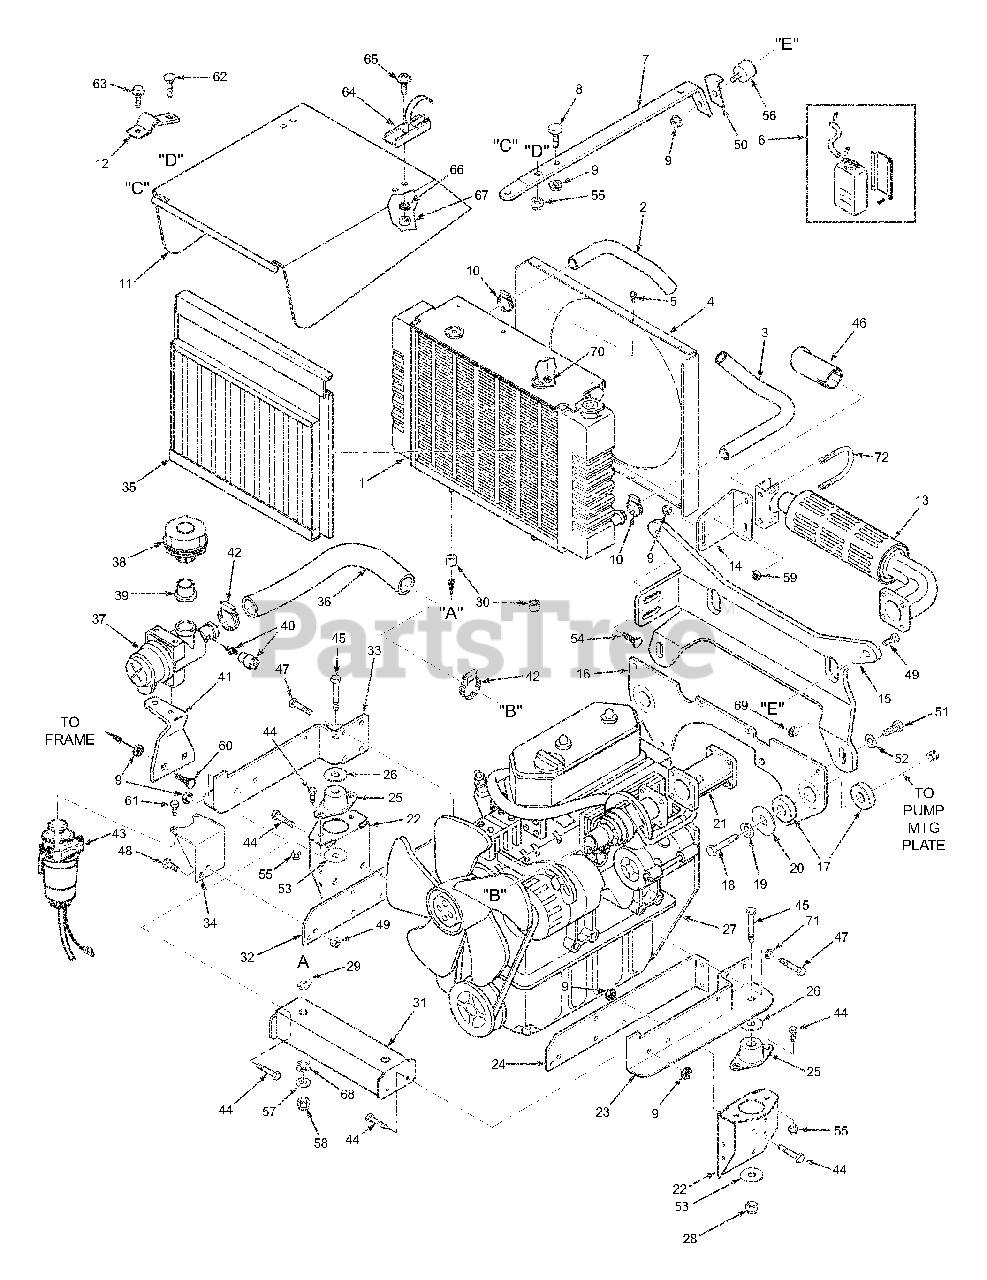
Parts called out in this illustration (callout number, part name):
1	Radiator
2	Hose, Upper Radiator
3	Hose, Lower Radiator
4	Shroud, Fan
5	Screw. #10-32 x 1/2"
6	Coolant Tank Assembly w/hose
7	Support Bracket, Hood
8	Bumper, Rubber
9	Nut, Serrated Flange 5/16-18
10	Clamp, 1-1/2" Dia.
11	Hood Weldment
12	Hinge, Hood
13	Muffler with Guard
14	Brace, Muffler Support
15	Mounting Bracket, Hood
16	Mounting Bracket Weldment, Rear Engine Mount
17	Engine ISO Mount, Rear
18	Bolt, Hex Head 1/2-13 x 3-1/2"
19	Lockwasher, 1/2" Spring
20	Flatwasher, 1/2-.531 x 2.0 x .25
21	Manifold Extension, Exhaust
22	Mounting Bracket, Engine
23	Mounting Bracket Weldment, Engine L.H.
24	Mounting Bracket, Engine L.H.
25	Engine ISO Mount, Front
26	Flatwasher, 1/2-.531 x 2.0 x .25
27	Engine, Briggs & Stratton 31hp Diesel (Spec. #)
28	Nut, Elastic Stop 1/2-13
29	Bushing, Radiator Isolator
30	Bushing, Radiator ISO Mount
31	Support Bracket, Radiator
32	Mounting Bracket, Engine R.H.
33	Mounting Bracket Weldment, Engine R.H.
34	Mounting Bracket, Water Seperator
35	Debris Screen
36	Hose, Air Intake
37	Air Cleaner Assembly w/mounting Band
38	Pre Cleaner, Engine Air
39	Adapter, Pre Cleaner
40	Indicator, Air Cleaner
41	Bracket, Air Cleaner
42	Clamp, Hose 2-1/2" Dia.
43	Fuel Filter, Water Seperator
44	Bolt, Hex Head 5/16-18 x 3/4"
45	Bolt, Hex Head 1/2-13 x 2-1/2"
46	Elbow, Exhaust
47	Bolt, Hex Head M8-1.25 x 3mm
48	Bolt, Hex Head 3/8-16 x 1-1/4"
49	Bolt, Hex Head 5/16-18 x 3/4"
50	Catch Bracket, Hood Latch
51	Bolt, Hex Head 3/8-16 x 1-1/4"
52	Flatwasher, 3/8-.391 x .938 x .105
53	Flatwasher, 1/2-.531 x 2.13 x .1345
54	Bolt, Carriage 5/16-18 x 1"
55	Nut, Elastic Stop 5/16-18
56	Rubber Isolator
57	Flatwasher, 7/16-.469 x 2.0 x .1345
58	Nut, Center Lock 7/16-14
59	Nut, Elastic Stop 5/16-18
60	Bolt, Carriage 5/16-18 x 3/4"
61	Bolt
62	Bolt, Carriage 5/16-18 x 1"
63	Bolt, Hex Head 5/16-18 x 3/4" Serr. Flange
64	Latch, Hood
65	Screw, #10-32 x .375
66	Lockwasher, #10 Spring
67	Nut, #10
68	Ring, Isolator
69	Nut, Elastic Stop 3/8-16
70	Nut, Elastic Stop #10-32
71	Lockwasher, 5/16 Spring
72	Muffler Clamp 1-1/2" Dia.
